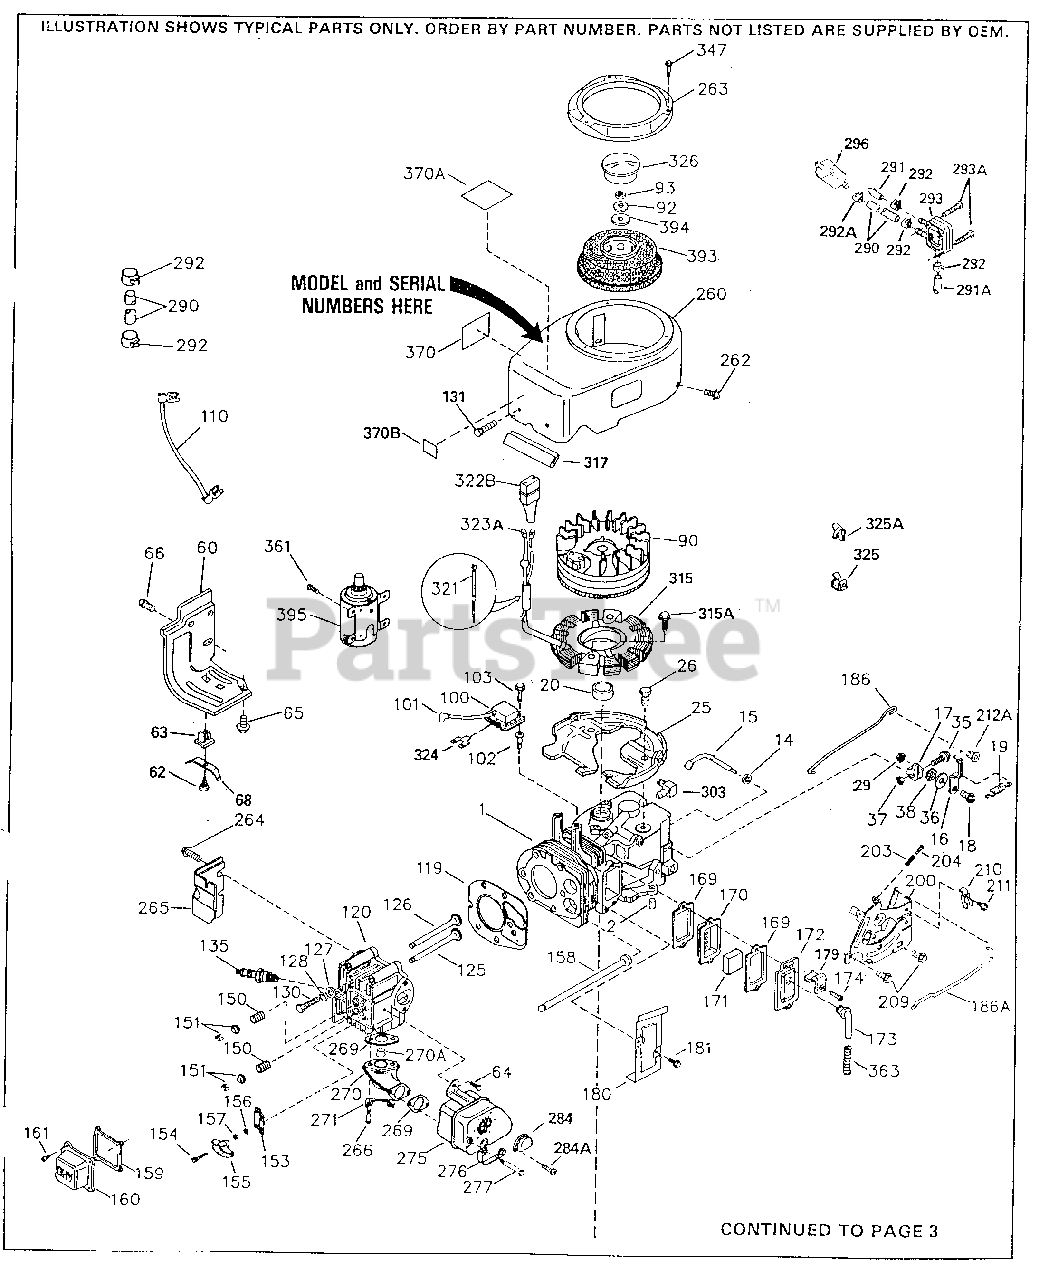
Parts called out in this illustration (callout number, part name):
1	"Cylinder (Incl. 2 & 20)
2	Dowel Pin
14	Flat Washer
15	Governor Rod
16	Governor Lever (Incl. 212A)
17	Governor Lever Clamp
18	Screw, 8-32 x 5/16"
19	Extension Spring
20	Oil Seal
25	Blower Housing Baffle
26	Screw, 1/4-20 x 5/8"
28	Lock Nut, 8-32
35	Screw, 10-32 x 3/4"
36	Lock Washer #8
37	Lock Nut, 10-32
38	Retaining Ring
60	Blower Housing Extension
65	Screw, 10-24 x 1/2"
66	Screw, 5/16-18 x 15/32"
90	Flywheel (W/Ring Gear)
92	Lock Washer
93	Flywheel Nut
100	Solid State Ignition
101	Spark Plug Cover
102	Solid State Mounting Stud
103	Screw, Torx T-15, 10-24 x 1"
110	Ground Wire
119	* Cylinder Head Gasket
120	Cylinder Head
125	Exhaust Valve (Std.)
125	Exhaust Valve (1/32" OS)
126	Intake Valve (Std.)
126	Intake Valve (1/32" OS)
128	Belleville Washer
130	Screw, 5/16-18 x 2-45/64"
135	Resistor Spark Plug (RN4C) also avail able in Packaged Part #740069
150	Valve Spring
151	Valve Spring Keeper
153	Push Rod Guide
154	Rocker Arm Stud
155	Rocker Arm
156	Lock Washer
157	Lock Nut, 5/16-24
158	Push Rod
159	* Rocker Arm Cover Gasket
160	Rocker Arm Housing
161	Screw, T-30, 1/4-20 x 1/2"
169	* Breather Gasket
170	Breather Body
171	Breather Element
172	Valve Cover
173	Breather Tube
174	Screw, 10-24 x 1/2"
180	Blower Housing Extension
181	Screw, 10-24 x 9/16"
186	Governor Link
200	Control Bracket (Incl. 203 & 204)
203	Compression Spring
204	Screw, 6-32 x 21/32"
207	Choke Link
209	Screw, 10-32 x 7/16"
210	Conduit Clip
211	Screw, 10-32 x 3/8"
212A	Bushing
238	Screw, 10-32 x 5-1/4"
245A	Pre-Cleaner Air Filter also available in Packaged Part #740015B
260	Blower Housing
261	Screw, T-30, 1/4-20 x 1/2"
262	Screw, T-40, 5/16-24 x 21/32"
263	Trim Ring
264	Screw, 5/16-18 x 5/8"
264A	Screw, 5/16-18 x 5/8"
265	Cylinder Head Cover
266	Screw, 5/16-18 x 1-1/4"
269	* Exhaust Manifold Gasket
270	Exhaust Manifold
270A	Exhaust Port Liner
271	Locking Plate (Manifold)
290	Fuel Line
292	Fuel Line Clamp
296	Fuel Filter (Incl. 292) also availabl e as Packaged Part #740003B
308	Filler Tube Clip
308A	Fill Tube Clip
315	Alternator Coil (3/5 Split) Incl. 321 , 322,323
325	Wire Clip
326	Blower Housing Plug
337	Deflector
347	Screw, 10-32 x 9/16"
361	Screw, Torx T-30, 5/16-18 x 15/32"
370	Instruction Decal
370A	Decal - Important Lubrication - SAE 3
395	Electric Starter Motor (12 Volt) (Inc l. 361)
